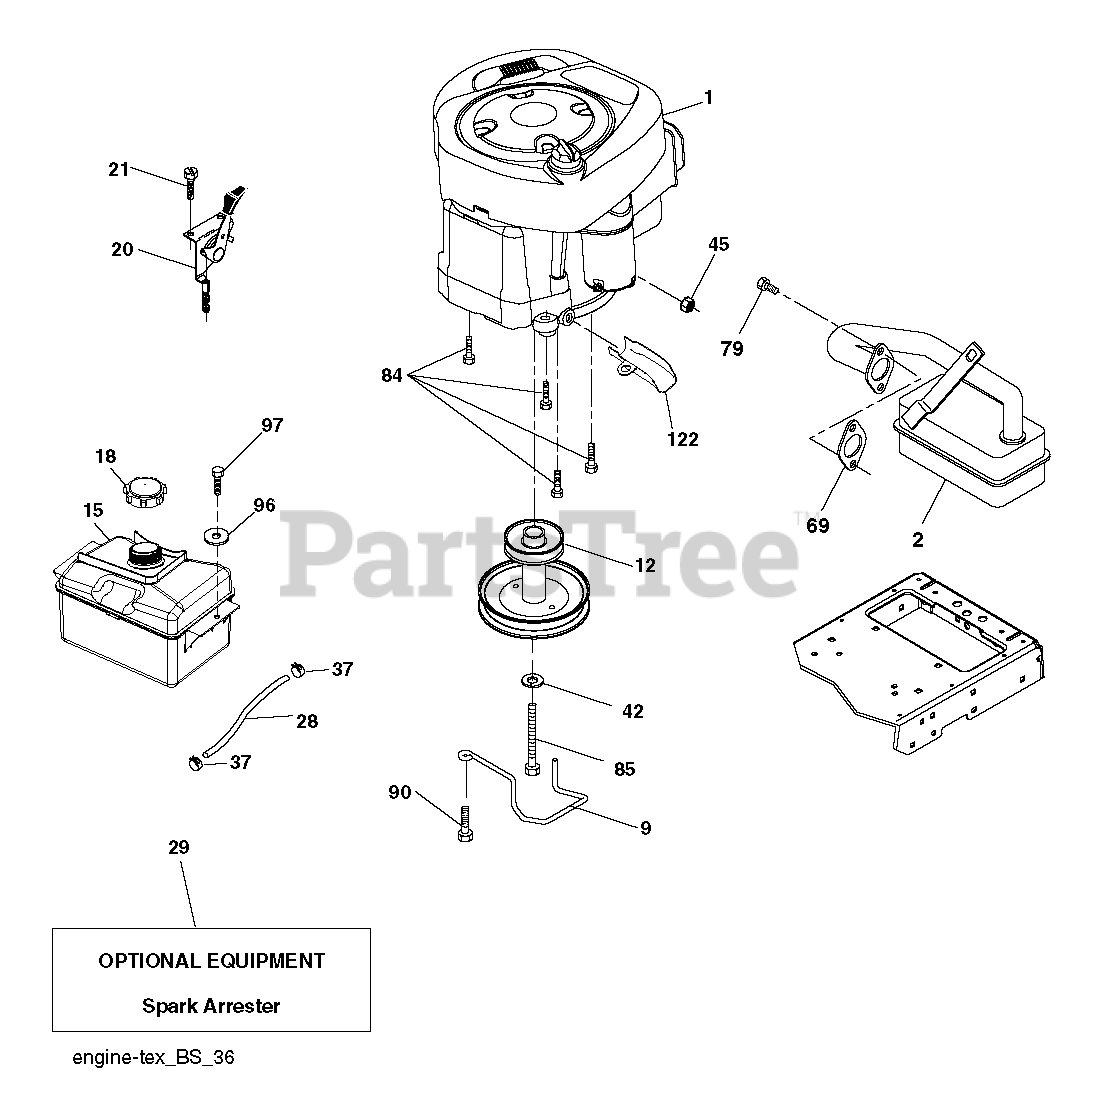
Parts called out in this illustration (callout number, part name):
9	KEEPER.BELT.ENGINE.3.25
12	PULLEY ENGINE
18	CAP ASM.FUEL.2.25"FR.
20	CONTROL.TH/CK.C.
21	SCREW.#10 X 0.750.BOS THREAD
28	LINE.FUEL.20
29	ARRESTER SPARK (OPTIONAL)
37	HOSE CLAMP
42	LOCKWASHER
45	NUT
69	REPL BY 532 27 22-93
79	SCREW.SOCKET HD.5/16-1
84	SCREW.3/8-16
85	BOLT HEX 7/16-20X4-1/4"
90	SCREW 3/8-16X1
97	SCREW HEXWSHR 1/4-20X3/4
122	EXTENSION DRAIN OIL
